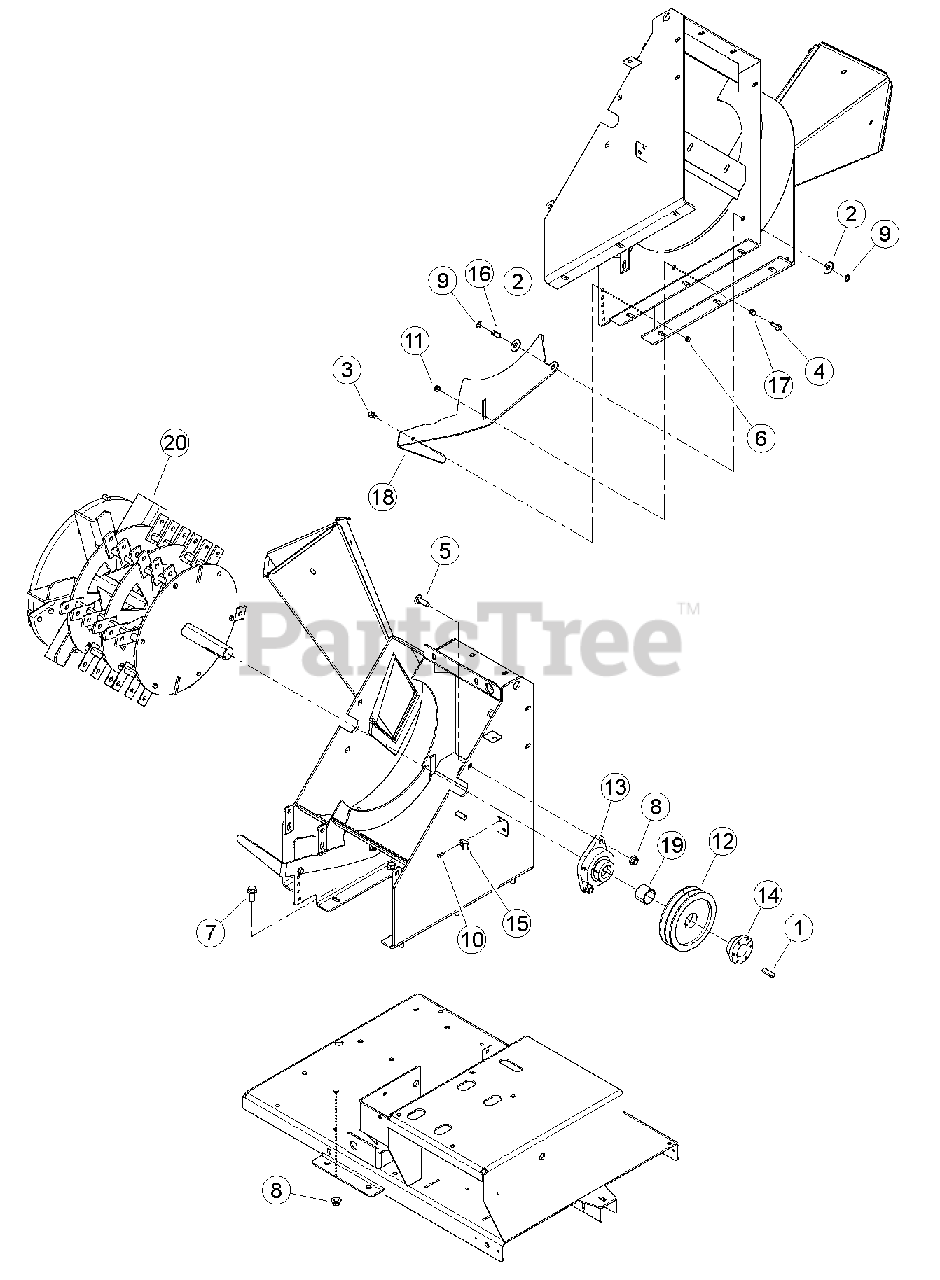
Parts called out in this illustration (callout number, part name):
1	KEY, 3/8 SQ X 1-1/2
2	WASHER, 1/2 FLAT
3	BOLT, 5/16 X 3/4 FLANGE NC
4	BOLT, 5/16 X 1 FLANGE NC
5	BOLT, 1/2 X 1-1/2" GR5 CRG ZP
6	NUT, 5/16" CENTERLOCK NC ZP
7	BOLT, 1/2-13 X 1-1/4 SERRATED FLANGE
8	NUT, 1/2 SPIRAL LOCK NC ZP
9	CLIP, 1/2" E
10	RIVET, AL BLIND 1/4 X 3/4 DOME HEAD
11	NUT, 5/16-18 NYLOCK FLANGE
12	SHEAVE, 2B 6.6 SDS
13	BEARING, 2 BOLT FLANGE 1-1/2" BORE
14	BUSHING, SDS 1-1/2"
15	CLAMP, CABLE MOUNT
16	PIN, RETAINER
17	SPACER, .50 X .50
18	ADJUSTOR, SHREDDER
19	SPACER, 1-3/4" OD X 1-1/2" ID X 1-1/4"
20	ASSEMBLY, 5" CS ROTOR KNIVES
